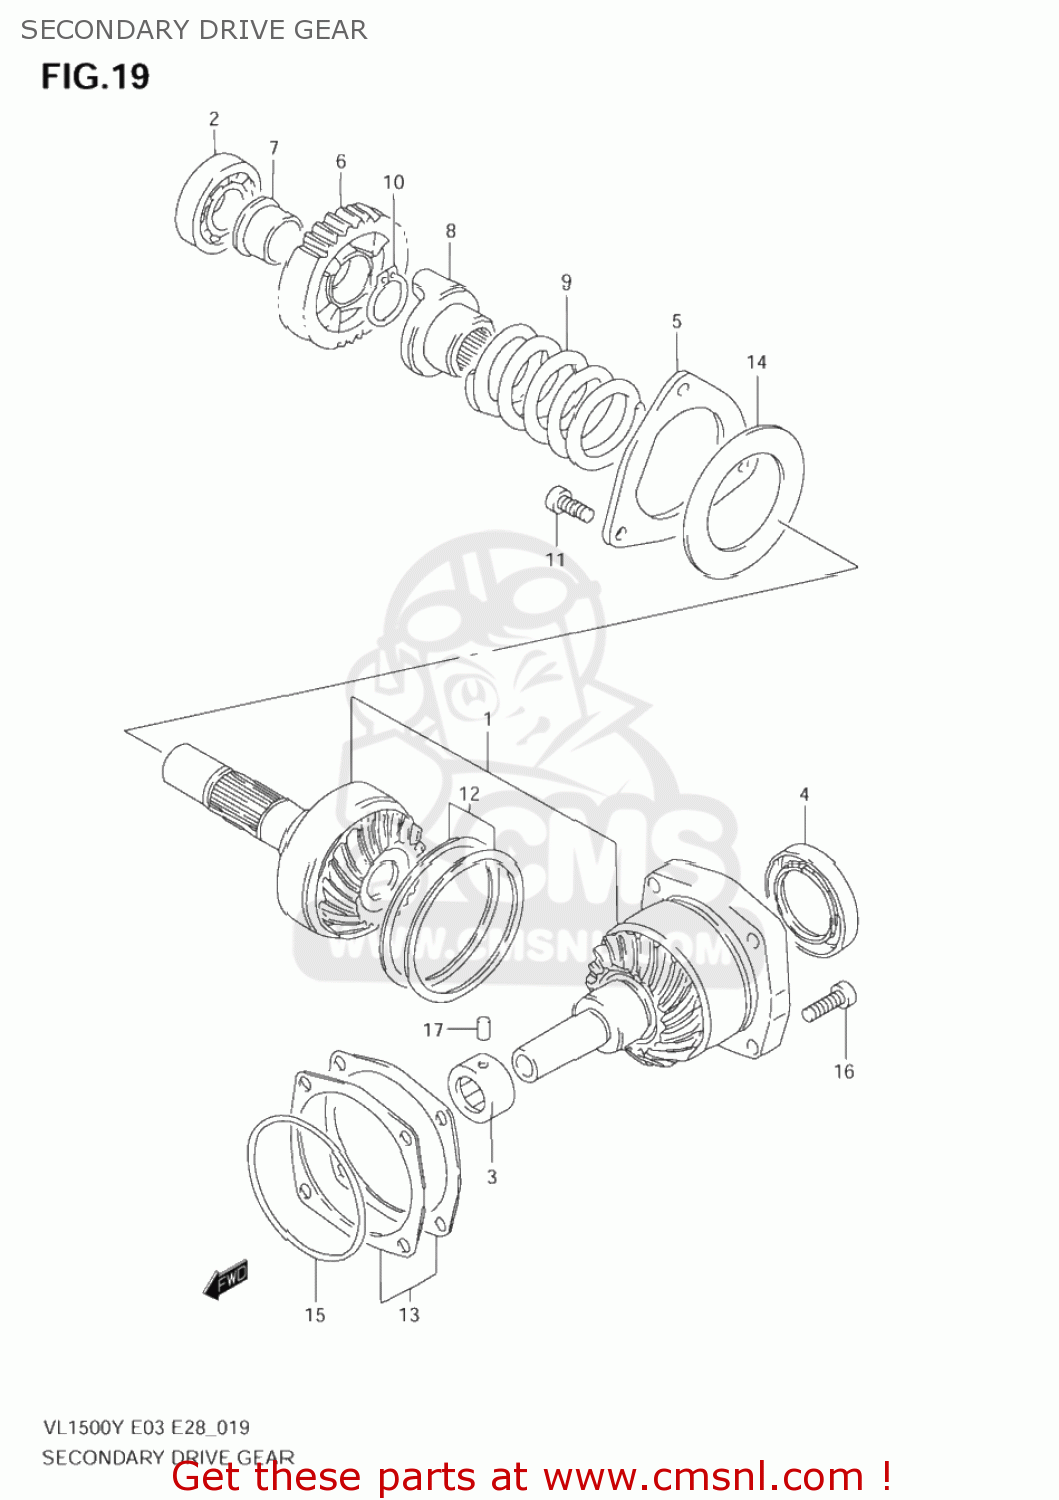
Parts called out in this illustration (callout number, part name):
1	GEAR & HOUSING SET,SECONDARY
2	BEARING(25X62X17)
3	BEARING(20X34X16)
4	SEAL,OIL(44X68X8)
5	STOPPER,SEC DRIVE BEARING
6	GEAR,OVER DRIVING DRIVEN
7	BUSHING,OD DRIVEN GEAR
8	DOG,OUTPUT CAM
9	SPRING
10	CIRCLIP
11	BOLT
12	SHIM SET,SEC DRIVE
13	SHIM SET,SEC DRIVEN
14	WASHER(57X90X3)
15	O RING(D:3.7,ID:76.5)
16	BOLT
17	PIN
